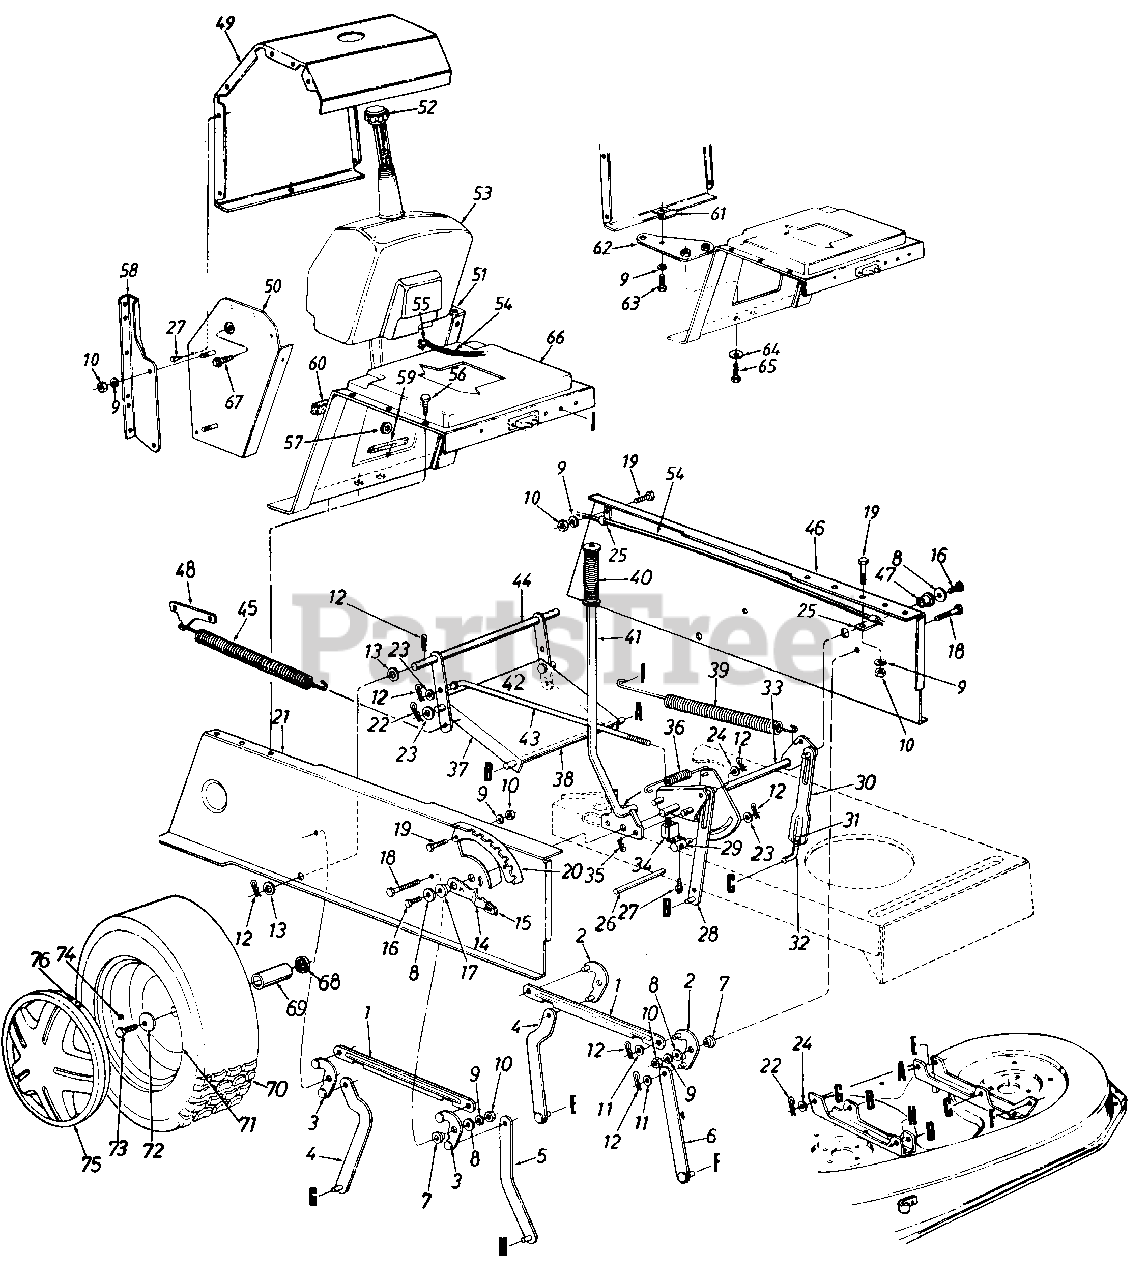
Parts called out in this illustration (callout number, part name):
1	Connecting Rod
2	Pivot Link Ass'y.-L.H.
3	Pivot Link Ass'y.-R.H.
7	Shld. Spacer.318" I.D.
8	Fl-Wash. 344" l.D. x 1.125"
9	L-Wash. 5/16" I.D.
10	Hex Nut 5/16-18 Thd.
12	Cotter Pin 1/8" Dia.
13	Fl-Wash. .635" I.CJ. x 1.0" O.D.
14	Deck LiR-Down Stop
16	Hex Wash. TT-Tap Scr. 5/16-18 x .75" Lg.
17	Flange Brg. .G3" I.D.
18	Hex Wash. TT-Tap Scr. 5/16-18 x.875" Lg.
19	Hex Bolt 5/16-18 x .75" Lg.
20	Index Brkt.
21	Upper Frame-R.H.
22	Inter. Cotter Pin 1/2" Dia.
23	Fl-Wash. 385" l.D. x 87" O.D.
24	Fl-Wash. .531" I.D. x 93" O.D.
26	Running Board Rod
27	Truss Mach. Scr. #10 x .5" Lg.
31	Hex Jam Nut 1/2-20 Thd. (Gr. 5)
32	Lift Link Adjuster
33	Lift Shaft Ass'y.
34	Safety Switch
35	Inter. Cotter Pin 3/8" Dia.
36	Extension Spring
37	Stabilizer Bracket
38	Shaft 1/zn Dia. x 10.28" Lg.
39	Extension Spring
40	Grip
41	Deck LiR Handle Ass'y.
42	Weld Pin .375" Dia. x 1.25" Lg.
43	Disengagement Rod
44	Stabilizer Shaft Ass'y.
45	Extension Spring 7.58" Lg.
46	Upper Frame-L.H.
47	Flange Brg. .632" I.D. I
48	Spring Retainer
49	Gas Tank Housing
50	Side Panel Ass'y.-R.H.
54	Fuel Line
56	Hex Wash. AB-Tap 5/16 x .75" Lg.
57	Rubber Grommet
58	Mtg. Brkt.-R.H.
62	Hitch Bar Ass'y.
63	Hex Bolt 5/16-18 x 1.0" Lg. (Gr. 5)
64	Bell-Wash. .38" l.D. x .88"
65	Hex Wash. Tap Scr. 3/8-16 x .75" Lg.
66	Hitch Plate
67	Hex Wash. Hd. Tap Scr. t/4-20 x.38" Lg.
68	Fl-Wash. 76" l.D. x 1.49" O.D.
69	Sleeve .75" I.D. x 1.0" O.D.
71	Wheel Rim Only
72	Bell-Wash. .345" l.D. x .88"
73	Hex L-Bolt 5/16-24x .75" Lg.
74	Air Valve
75	Hub Cap
76	Spring Clip
